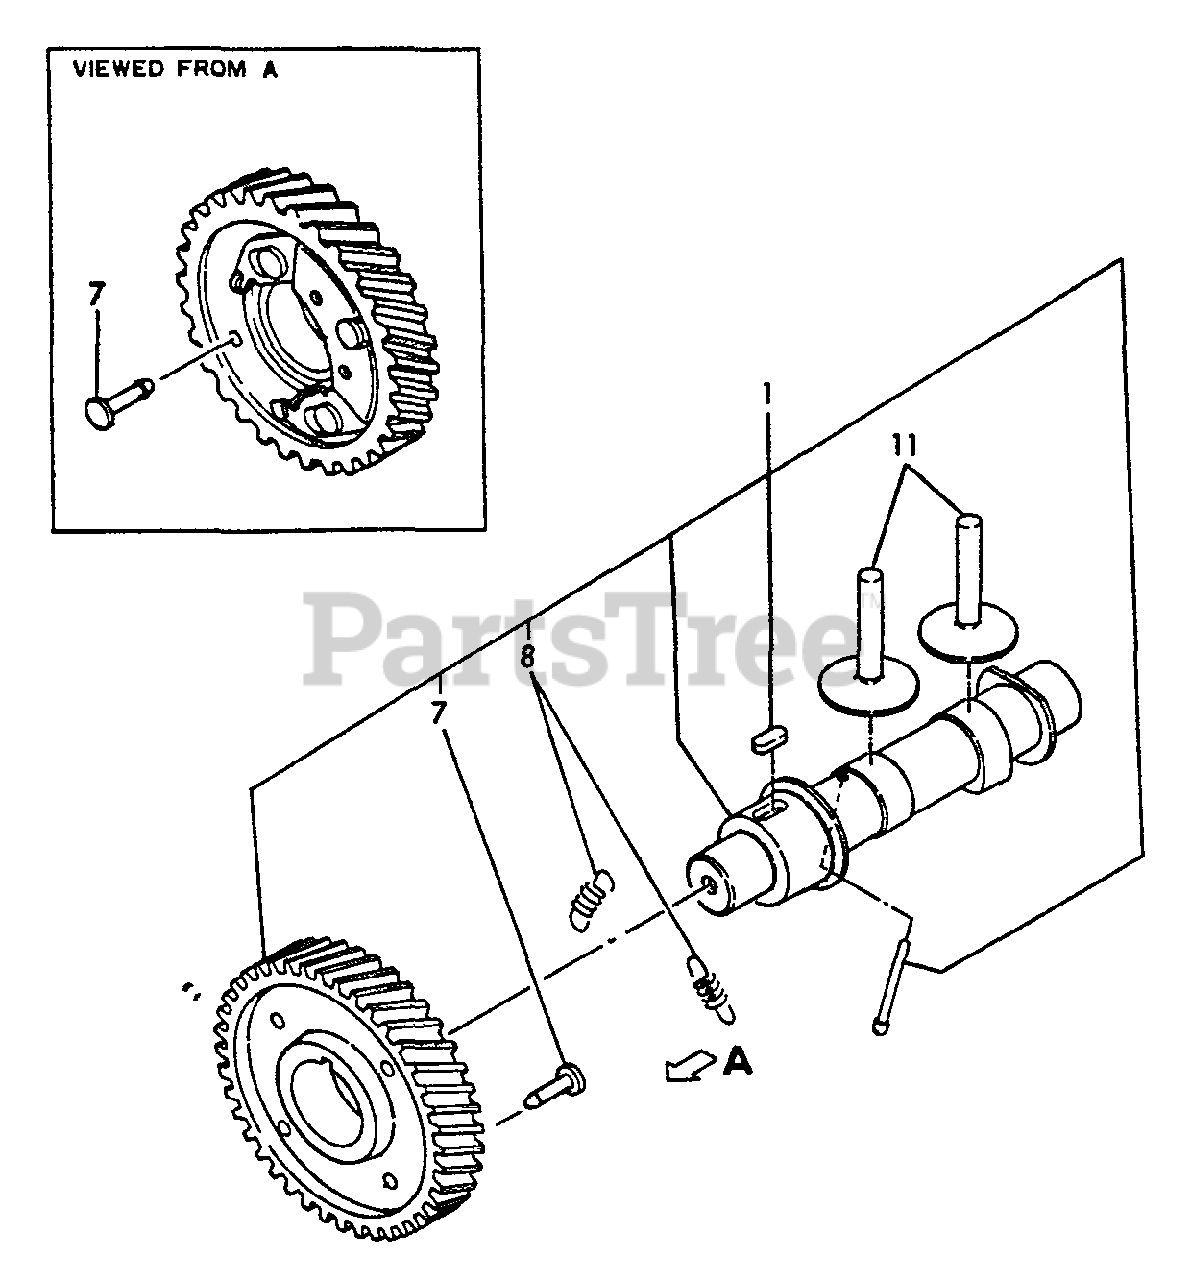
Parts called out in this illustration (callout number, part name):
1	CAMSHAFT ASSY
7	PIN, GUIDE - B
8	SPRING
11	TAPPET
